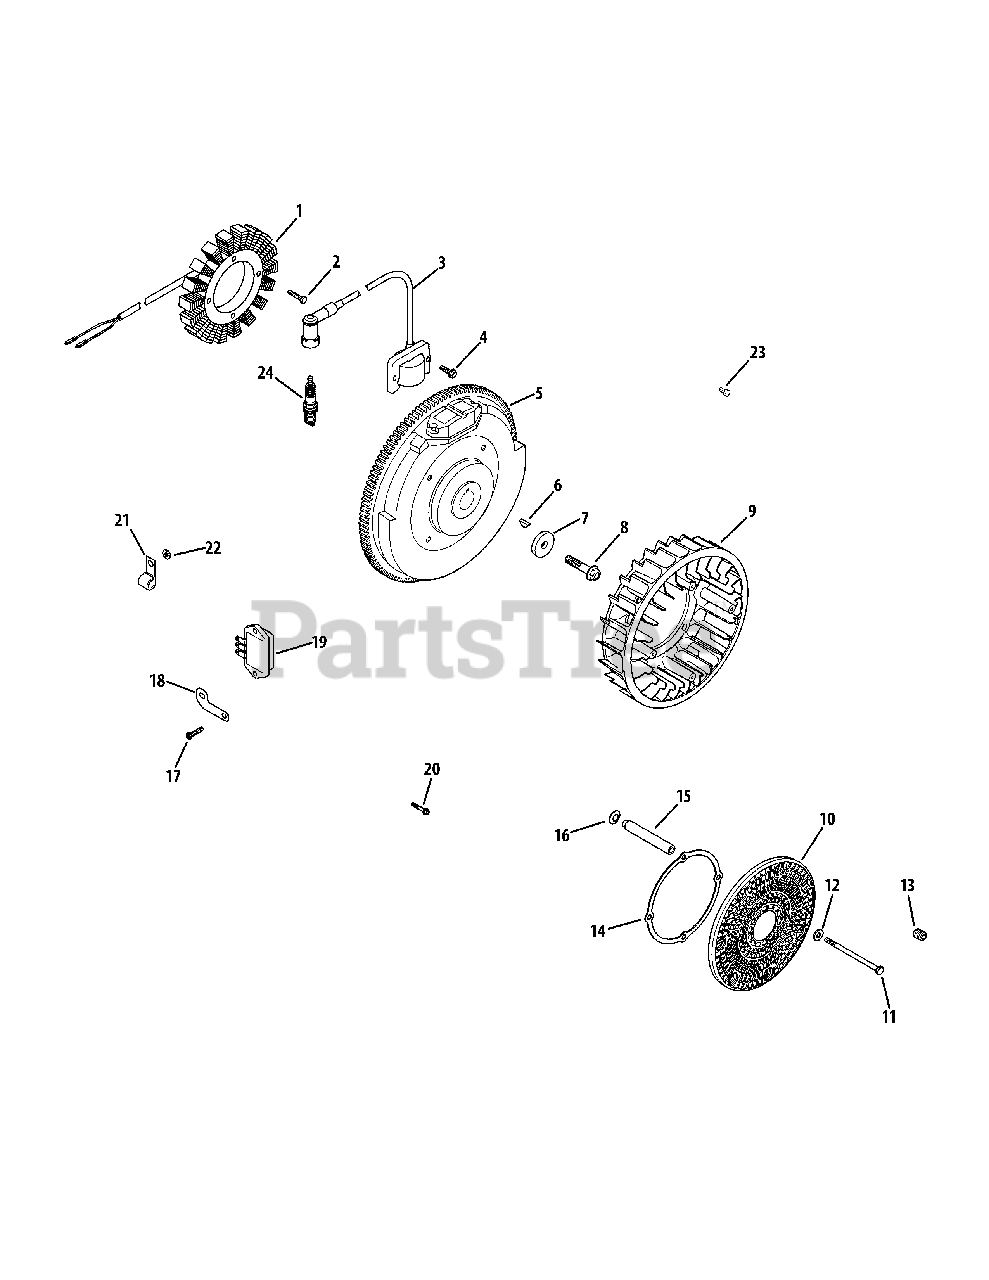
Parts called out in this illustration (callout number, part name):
1	15/20 Amp Stator Kit
2	Thread Forming Screw
3	Module Ignition Key (CDI Fixed)
4	Thread Forming Screw
6	Key, 3/16 x 5/8
7	Flat Washer, 13/32
8	Flange Screw, M10 x 1.5 x 45
9	Fan
11	Cap Screw, M6 x 1.0 x 99.5
12	Flat Washer, 1/4 x 5/8
13	Set Screw, #10-24 X 1/4
14	Support Ring
16	Spring Washer, 10 MM
17	Hex Flange Hi-Lo Screw
18	Ground Strap Bracket
19	Regulator/Rectifier
20	Flange Screw, M8 x 1.25 x 45
21	Cable Clip
22	Flat Washer, 1/4 x 1/2
23	Washer Head Tap Screw, #8-18 x 1/2
24	Spark Plug (Std.)
